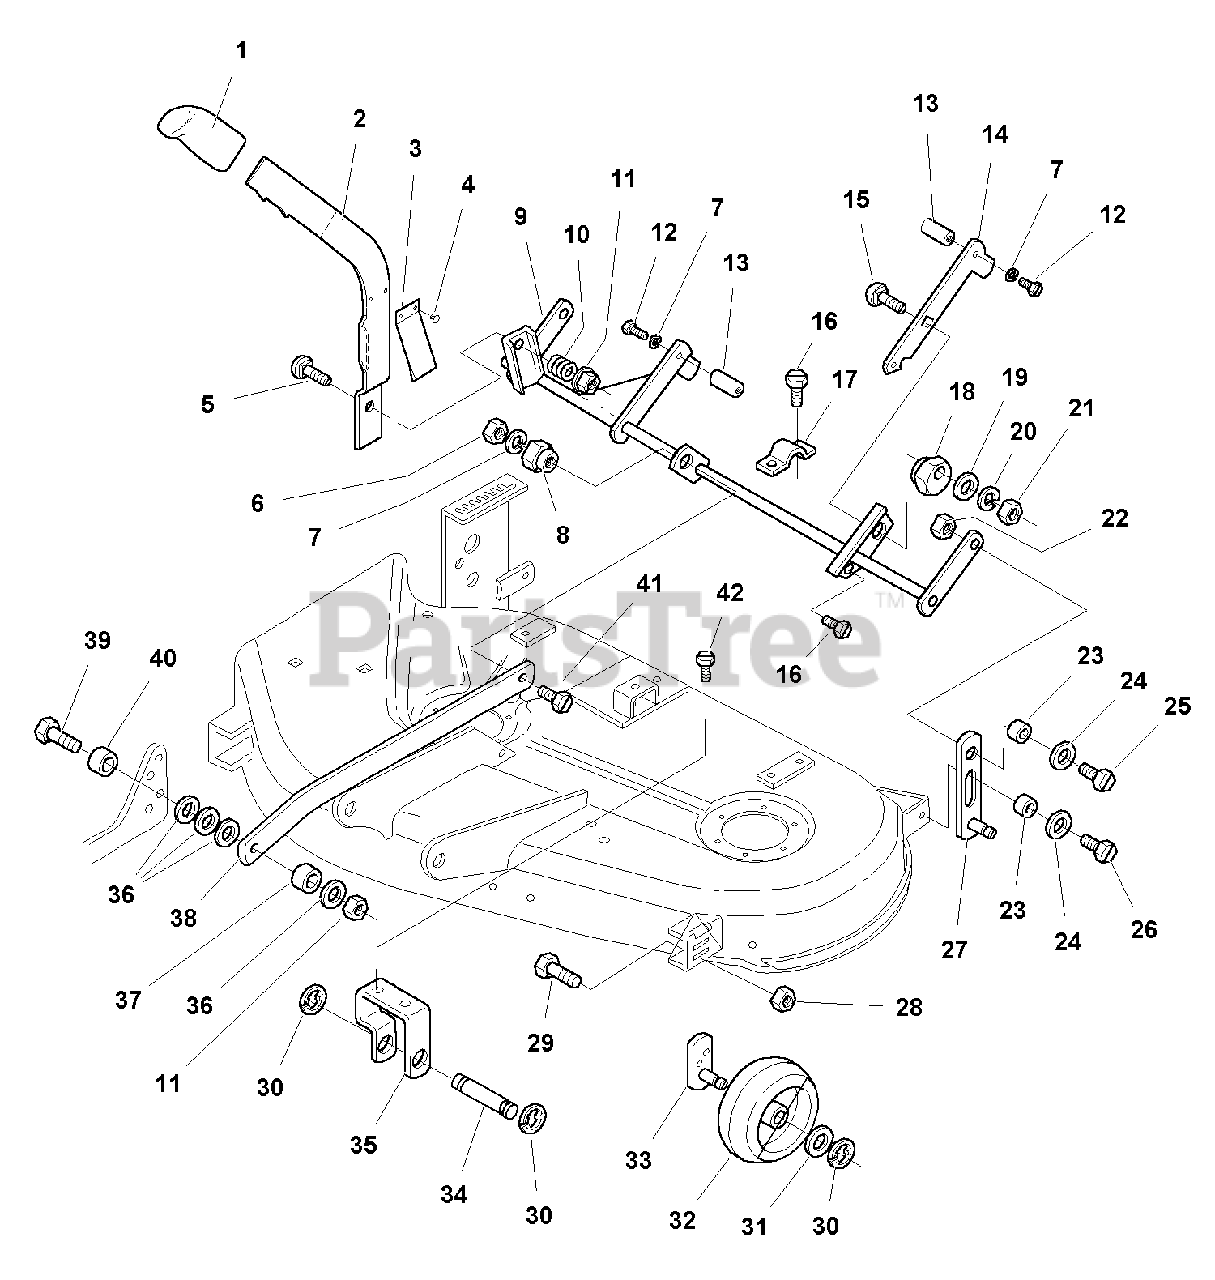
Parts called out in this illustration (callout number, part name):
2	ARM, Height Adjust (Includes Ref. Nos. 3 & 4)
5	CARRIAGE BOLT, 3/8-16 x 1-3/4
6	NUT, Hex, 3/8
7	WASHER, Lock, 3/8
8	NUT, Hex Adjusting, .99 DIA .687
9	ROCKER ARM ASSEMBLY
11	NUT, Flange Lock, 3/8
12	CAPSCREW, Hex Head, 3/8-16 x 1
13	SUPPORT, Mower
14	ARM ASSEMBLY, Rear Adjusting
15	CARRIAGE BOLT, 5/16-18 x 1-1/4
16	CAPSCREW, Hex Head, Taptite, 5/16-18 x 7/8
17	STRAP
19	WASHER
20	WASHER, Lock, 5/16
21	NUT, 5/16-18
22	NUT, Lock, 5/16-18
25	CAPSCREW, 5/16-18 x 1
26	CAPSCREW, Hex Head, Taptite, 5/16-18 x 1
27	ARM ASSEMBLY
28	NUT, Flanged 2-Way Lock, 1/4-20
29	CAPSCREW, Hex Head, 1/4-20 x 3/4
30	E-RING, 1/2
31	WASHER, 1/2
32	WHEEL, Gauge
33	ARM ASSEMBLY, Fixed
34	SHAFT, Gauge Wheel
35	BRACKET, Gauge Wheel
36	WASHER, Flat, 3/8
39	CAPSCREW, 3/8-16 x 1-1/4
41	CARRIAGE BOLT, 3/8-16 x 1-1/2
42	CAPSCREW, Hex Head, Taptite, 5/16-18 x 3/4
